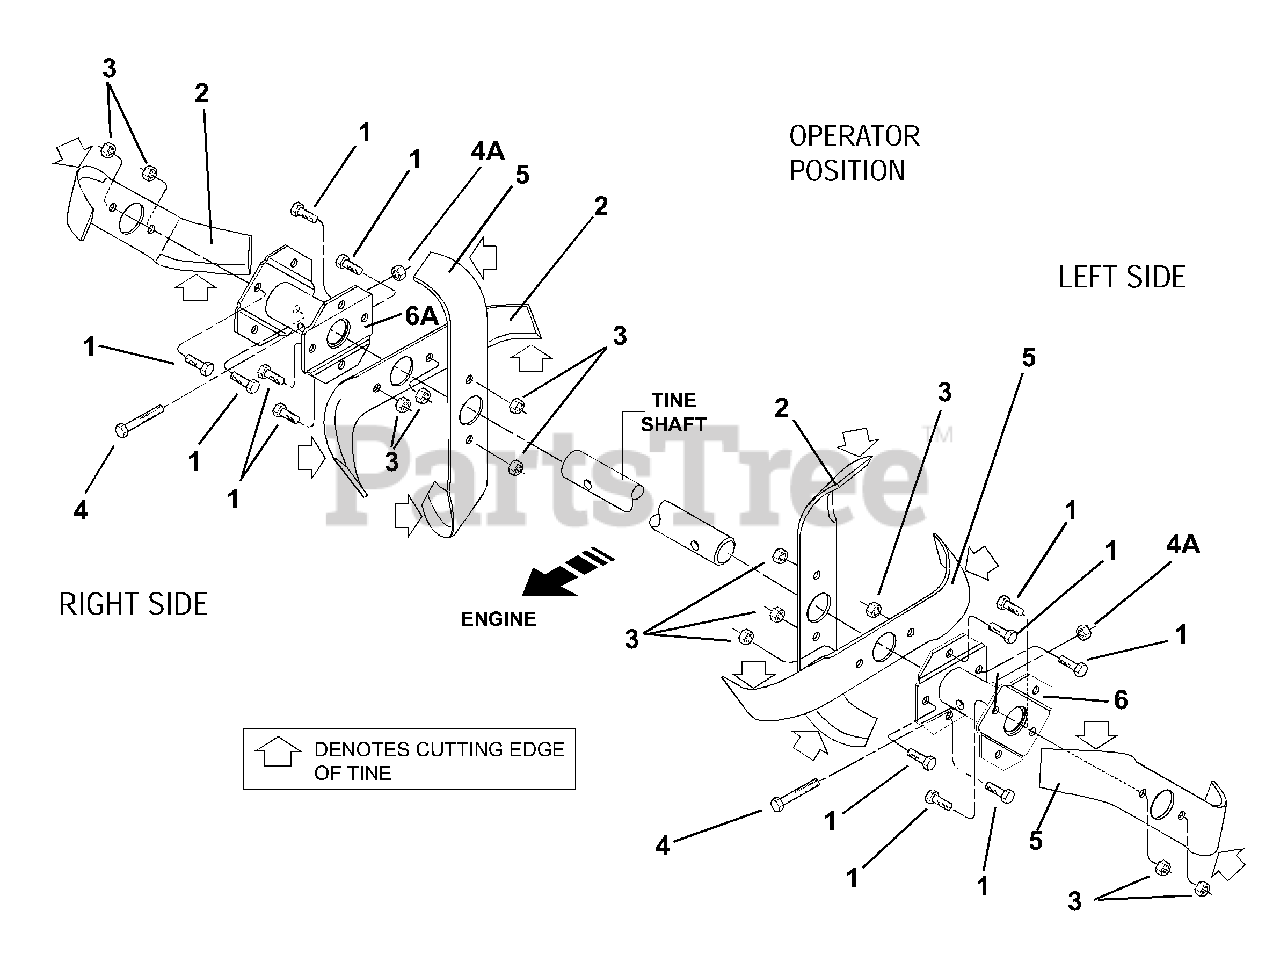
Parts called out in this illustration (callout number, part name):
1	Bolt-Hex Head, 5/16-18 x 3/4,Grade 5, Tine Mounting
2	Tine-Twin-Edged, Left-Facing
3	Locknut-Hex Hd., 5/16-18
4	Bolt-Hex Hd., 3/8-16 x 2 (tine holder to tiller shaft)
4A	Locknut- Hex Hd., 3/8-16
5	Tine-Twin-Edged, Right-Facing
6	Tine Holder- left side
6A	Tine Holder- right side
